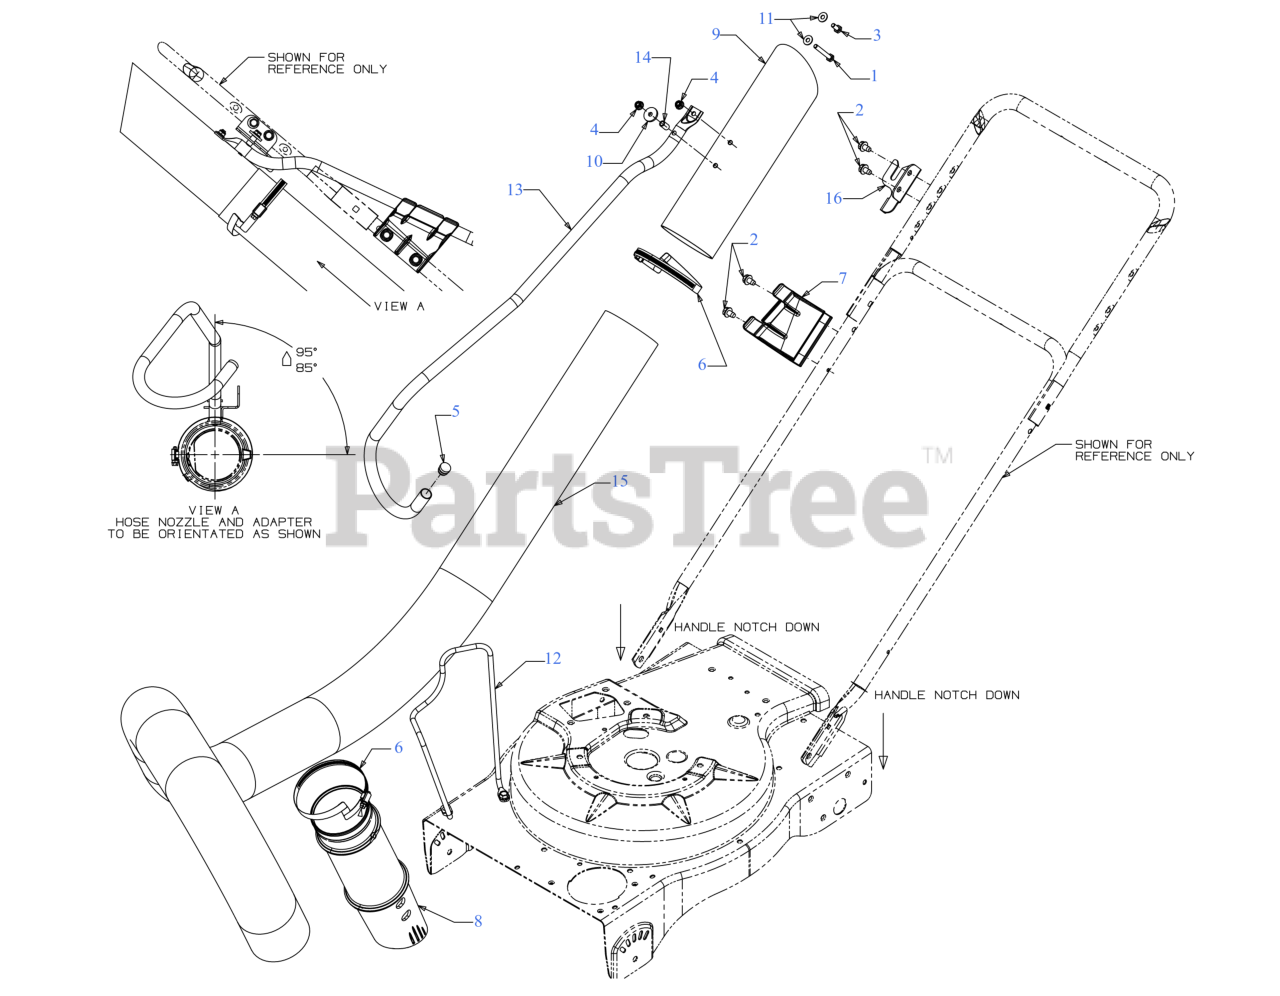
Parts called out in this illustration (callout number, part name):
1	SCREW 1/4-20 x 2 GR5
2	SCREW 5/16-18 x .500
3	SCREW 1/4-20 x .620 GR5
4	FLANGE LOCK NUT
5	HANDLE PLUG
6	SPIRAL HOSE CLAMP
7	CLIP-HANDLE NOZZ
8	VAC HOSE ADAPTER
9	HOSE NOZZLE 3.875
10	FLAT WASHER
11	FLAT WASHER .266X.625
12	HOLDER ROD
15	VACUUM HOSE 4.0 x 75.0
16	NOZZLE MOUNTING BRACKET
